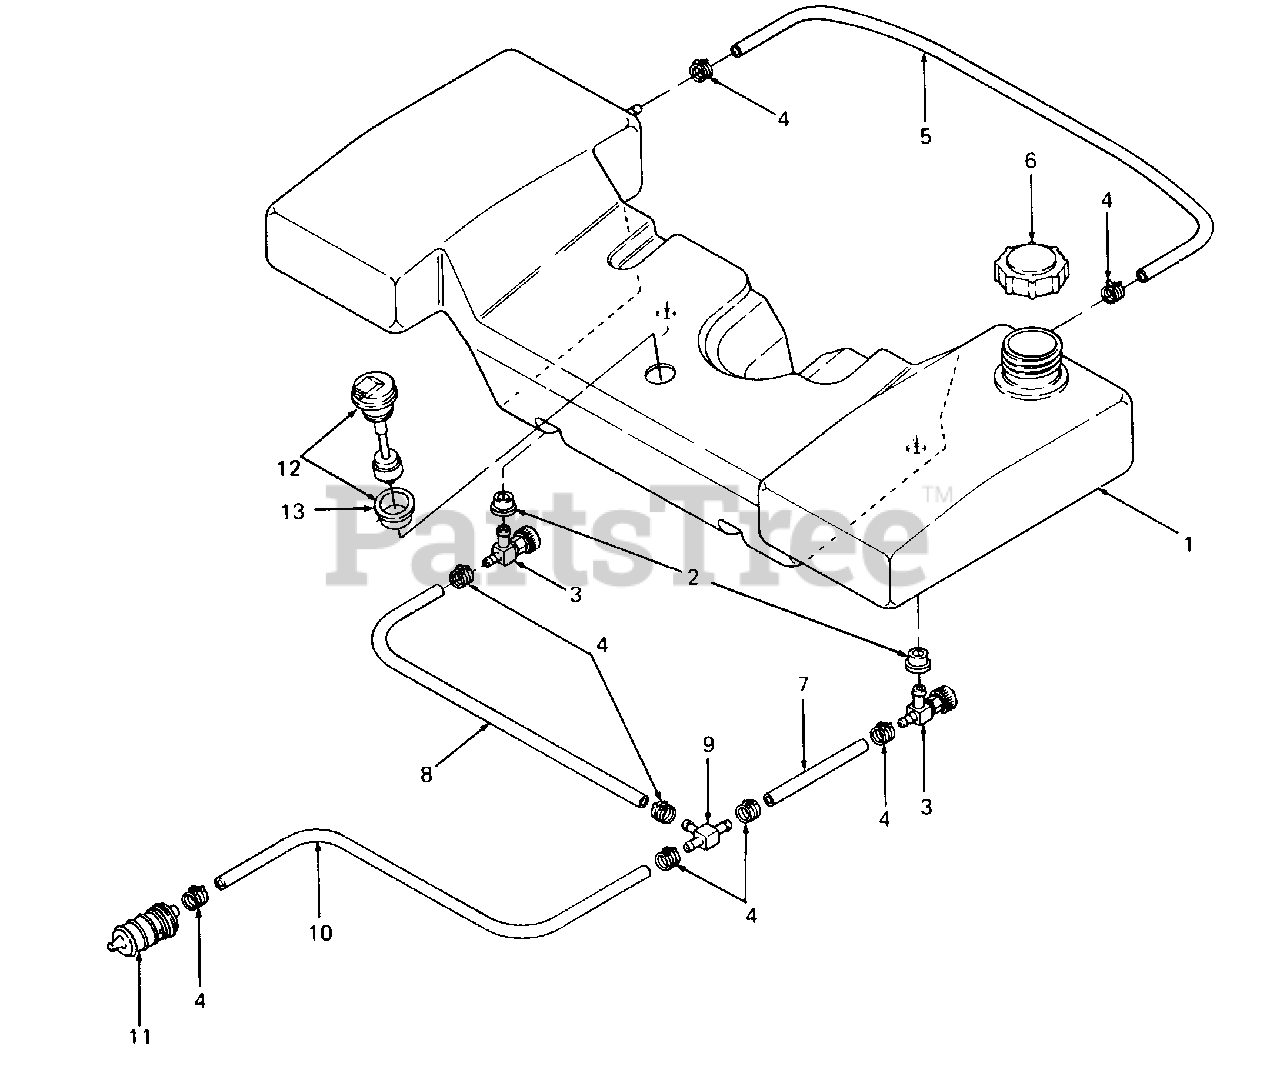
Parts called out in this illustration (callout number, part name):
1	Tank, Fuel
2	Bushing
3	Valve, Fuel Shutoff
4	Clamp, Hose
5	Line, Fuel -24" Lg
6	Cap, Fuel
7	Line, Fuel -5" Lg
8	Line, Fuel -19" Lg
9	T-Fitting
10	Line, Fuel -38" Lg
11	Filter, Fuel
12	Sensor, Low Fuel
13	Bushing, Rubber
